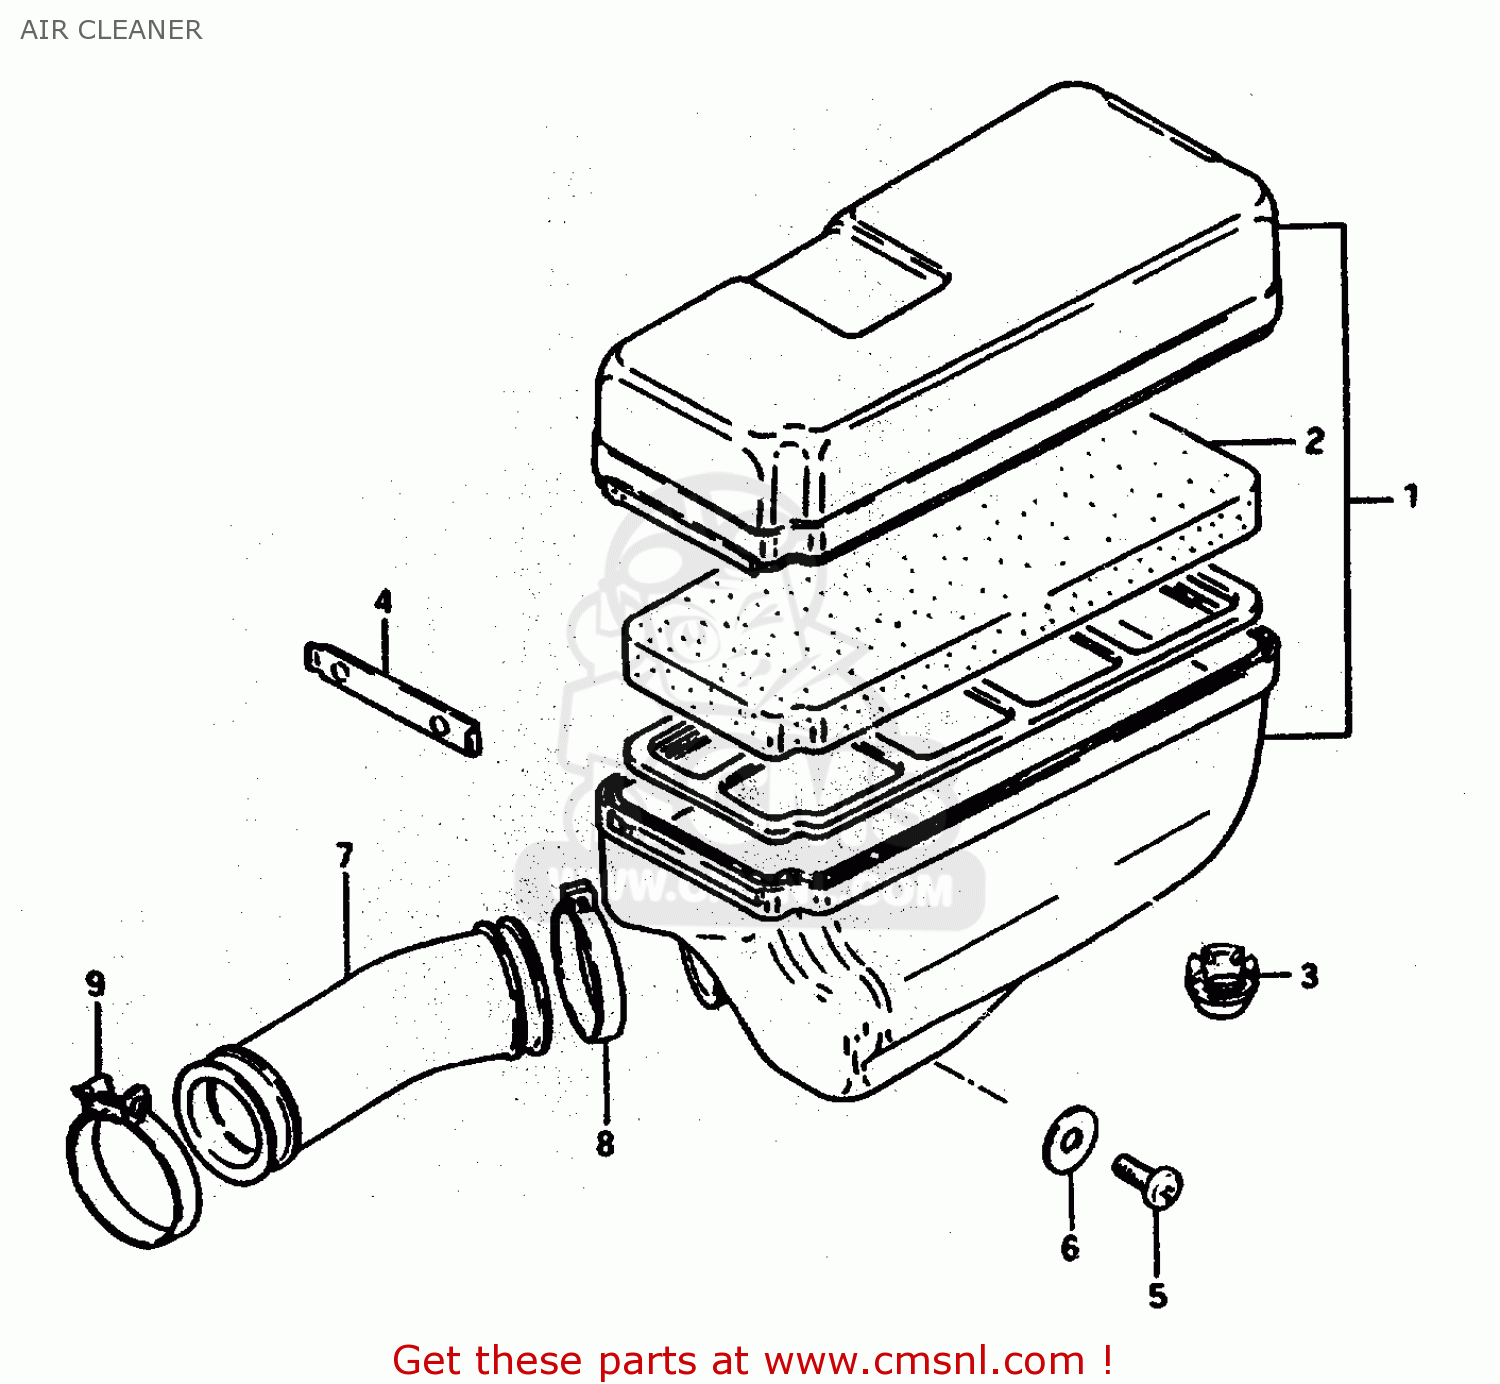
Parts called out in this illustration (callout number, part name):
1	CLEANER ASSY,A
2	FILTER
4	SLIDER
5	SCREW
7	TUBE,AIR CLEANER OUTLET
8	CLAMP
9	CLAMP
